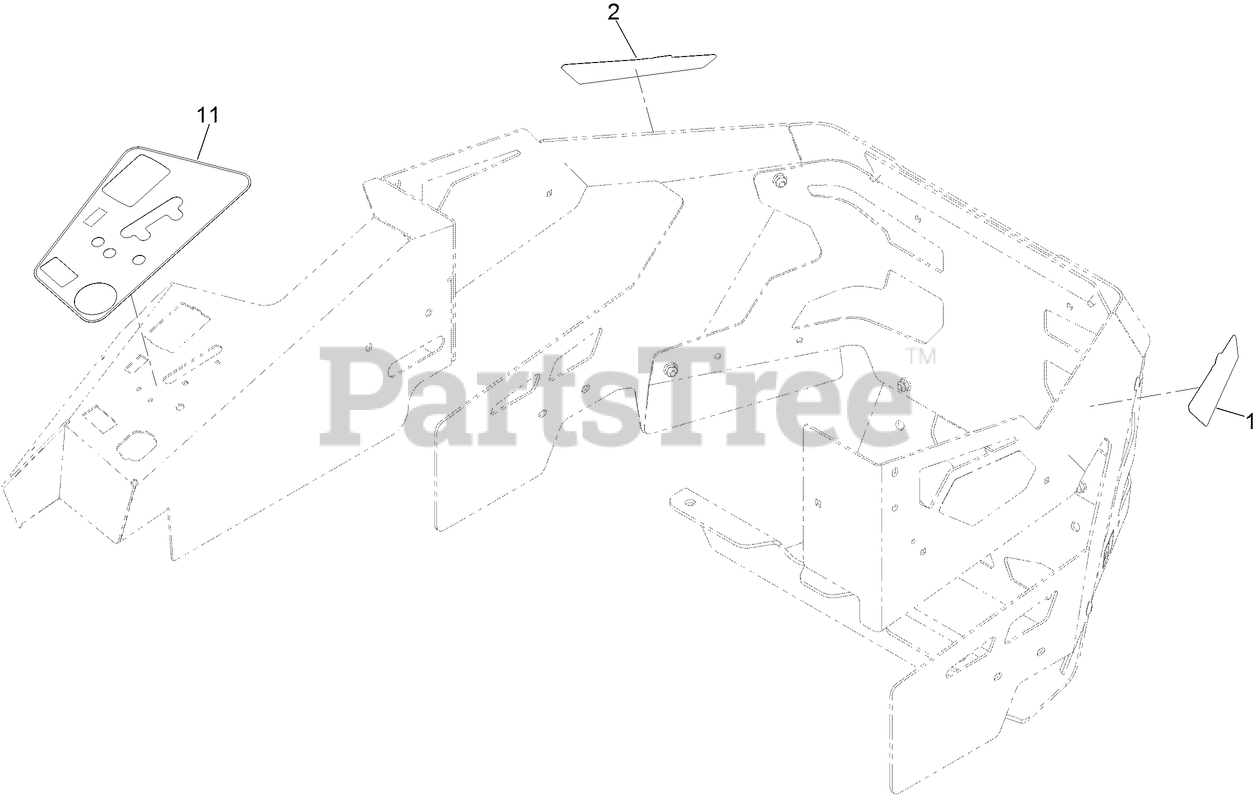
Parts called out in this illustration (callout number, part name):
1	DECAL - PRO
2	DECAL - PRO
11	DECAL-PANEL, TE CONTROL
